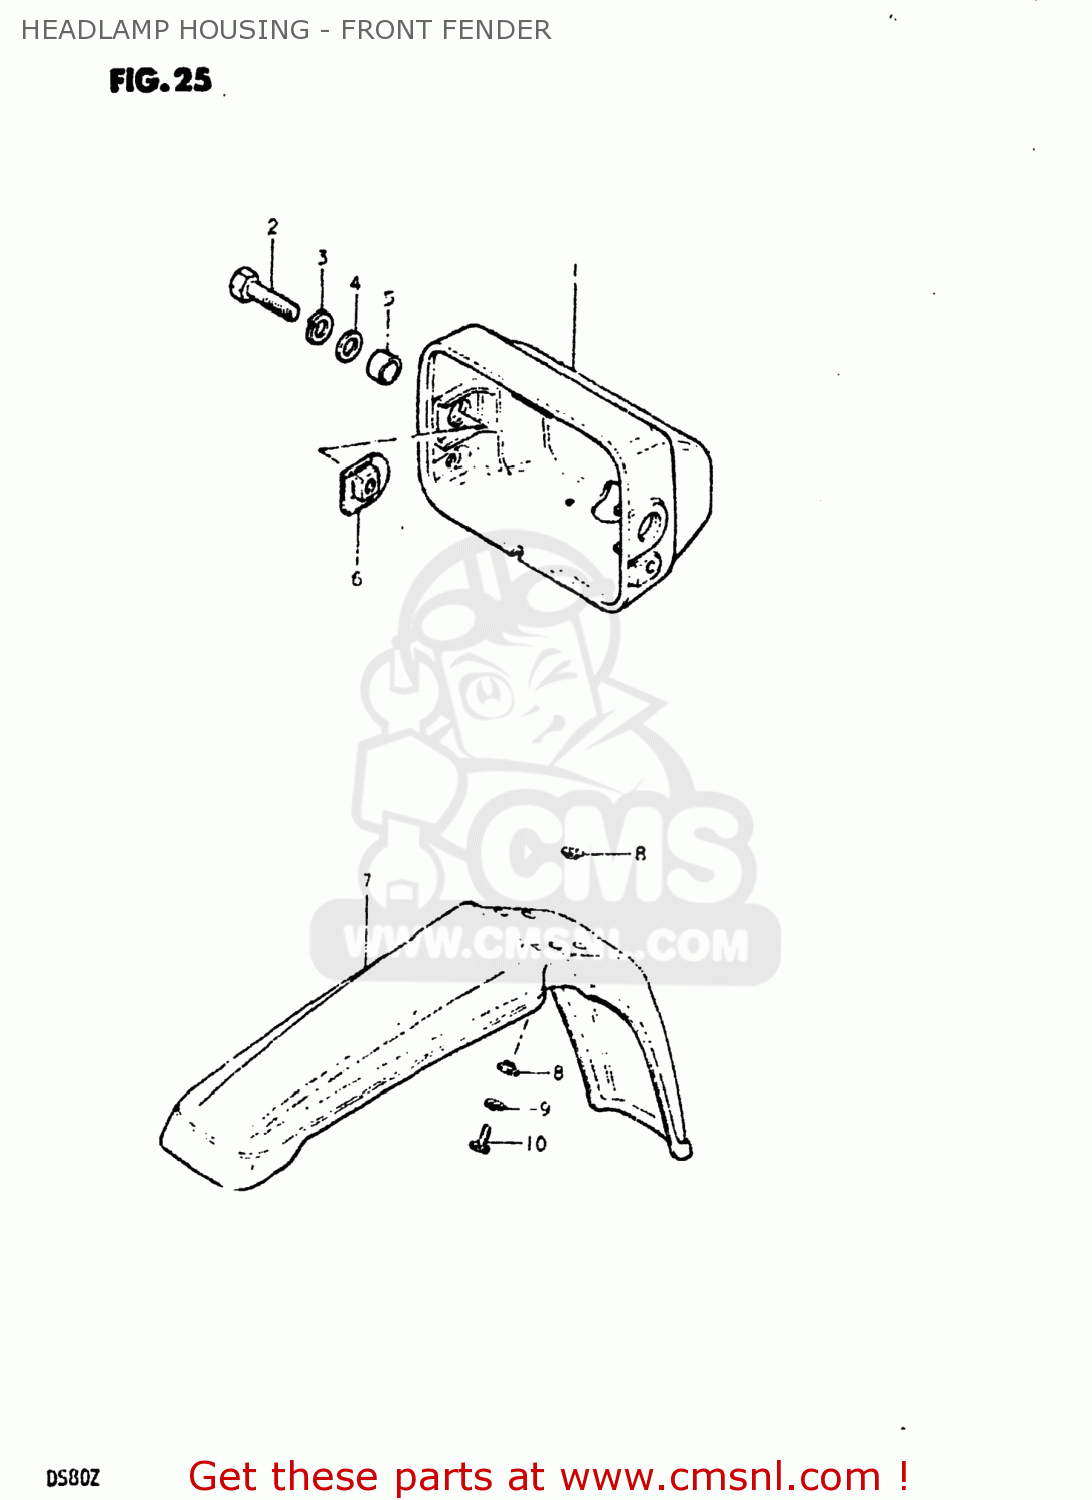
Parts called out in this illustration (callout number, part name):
1	HOUSING,HEADLAMP
2	BOLT
3	LOCK WASHER
4	WASHER
5	SPACER (8.8X12X7)
6	PLATE,HEADLAMP HOUSING
7	FENDER,FRONT
8	SPACER
9	LOCK WASHER
10	BOLT, UPPER
